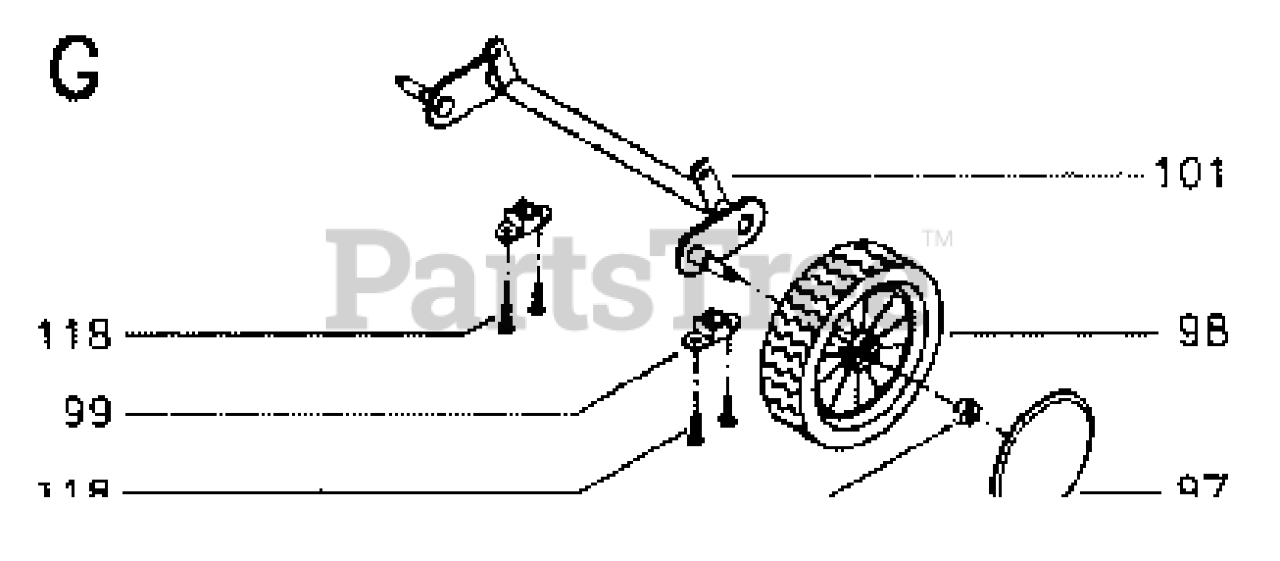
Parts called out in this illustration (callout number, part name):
1	SEAT.TH150.MS498.GRY.HUSQ.TEX
2	BRKT.PIVOT.FENDER
3	STRAP
6	NUT
7	SPRING COMPRESSION
8	BOLT.5/16-18UNCX3/4 W/SEMS.BLK
10	PAN.ASM.SEAT.3PT
21	BOLT.SHOULDER.5/16-18
37	NUT.71038.31-18.HEX.NYLOCK
40	HANDLE.SLIDE.SEAT.TEX.BLACK
41	SPRING.LATCH.SEAT.TEX
44	WASHER 13/32 X 2-3/8 X 12GA
101	SHAFT
